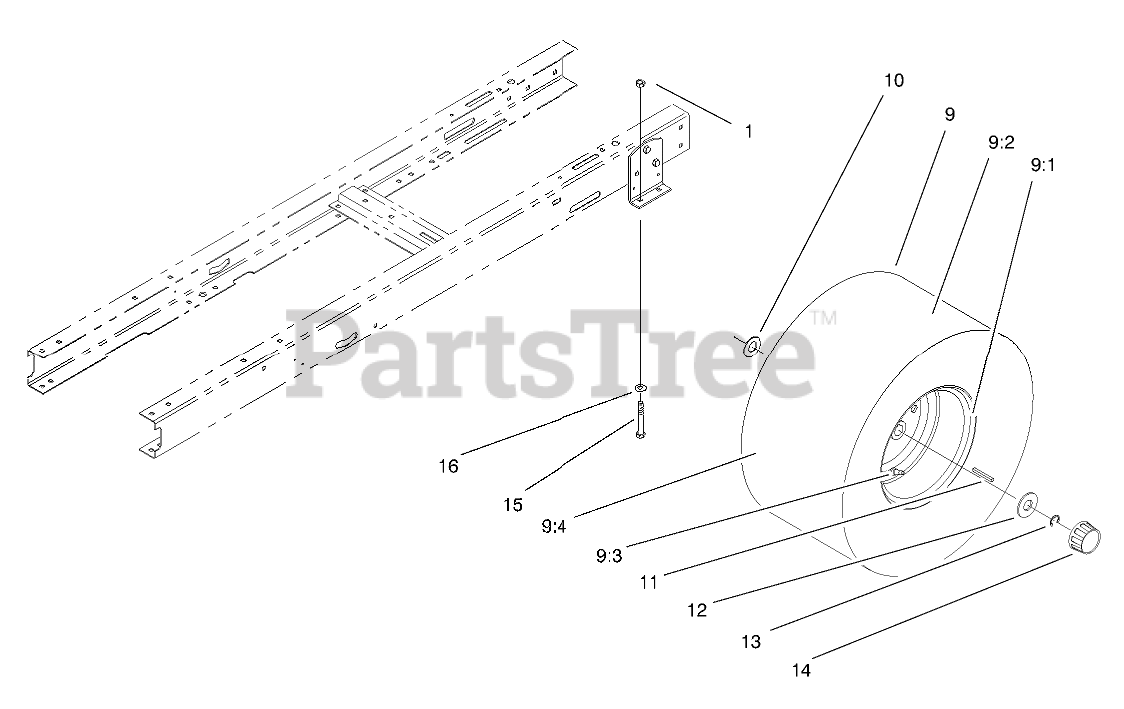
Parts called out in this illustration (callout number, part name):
1	NUT-LOCK, NI
9	Rear Wheel & Tire ASM
9:2	TIRE 18 X 9.50 X 8
9:3	STEM-VALVE
9:4	Tube
10	WASHER-THRUST
11	KEY-SQUARE
12	WASHER-PLAIN
13	E-RING
14	CAP-HUB
15	SCREW-HH
16	WASHER-PLAIN
